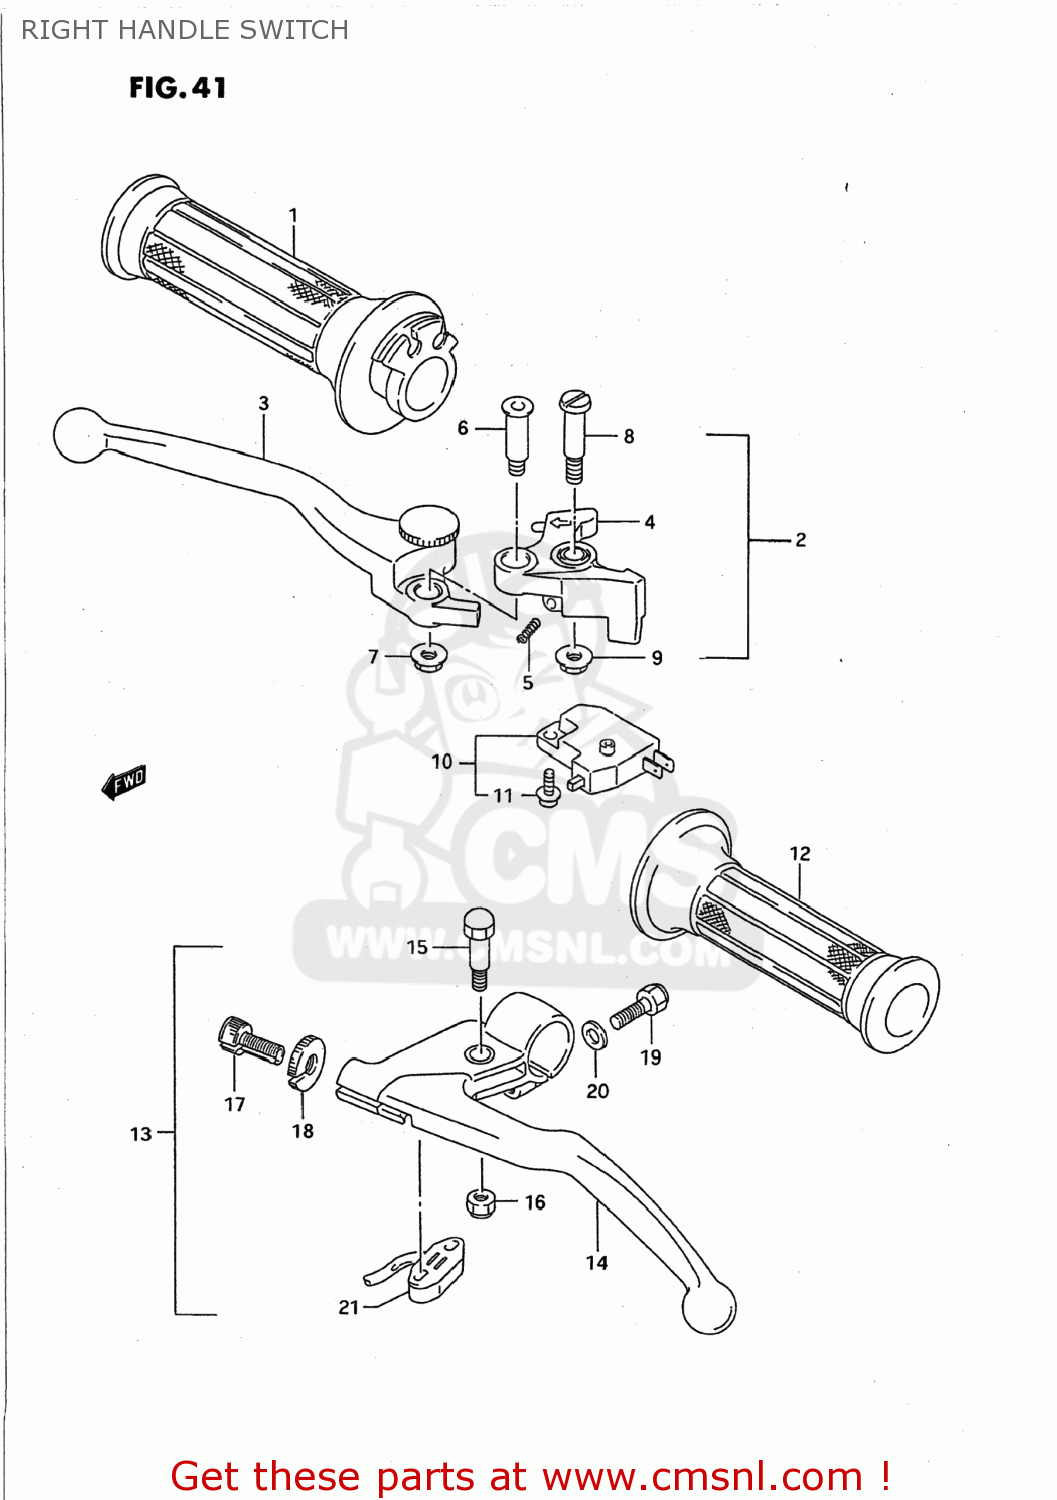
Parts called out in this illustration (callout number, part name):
1	GRIP,THROTTLE
2	LEVER ASSEMBLY,BRAKE
3	LEVER,ADJUST
4	KNOCKER
5	SPRING
6	BOLT,LEVER
7	NUT
8	BOLT,LEVER PIVOT
9	NUT 6MM
10	SWITCH ASSEMBLY,STOP
11	SCREW
12	GRIP,L
13	LEVER ASSY,CLUTCH
14	LEVER,CLUTCH
15	BOLT,LEVER PIVOT
16	NUT
17	ADJUSTER,CABLE
18	NUT,CABLE ADJUSTER
19	BOLT
20	WASHER
21	SWITCH ASSY,CLUTCH
